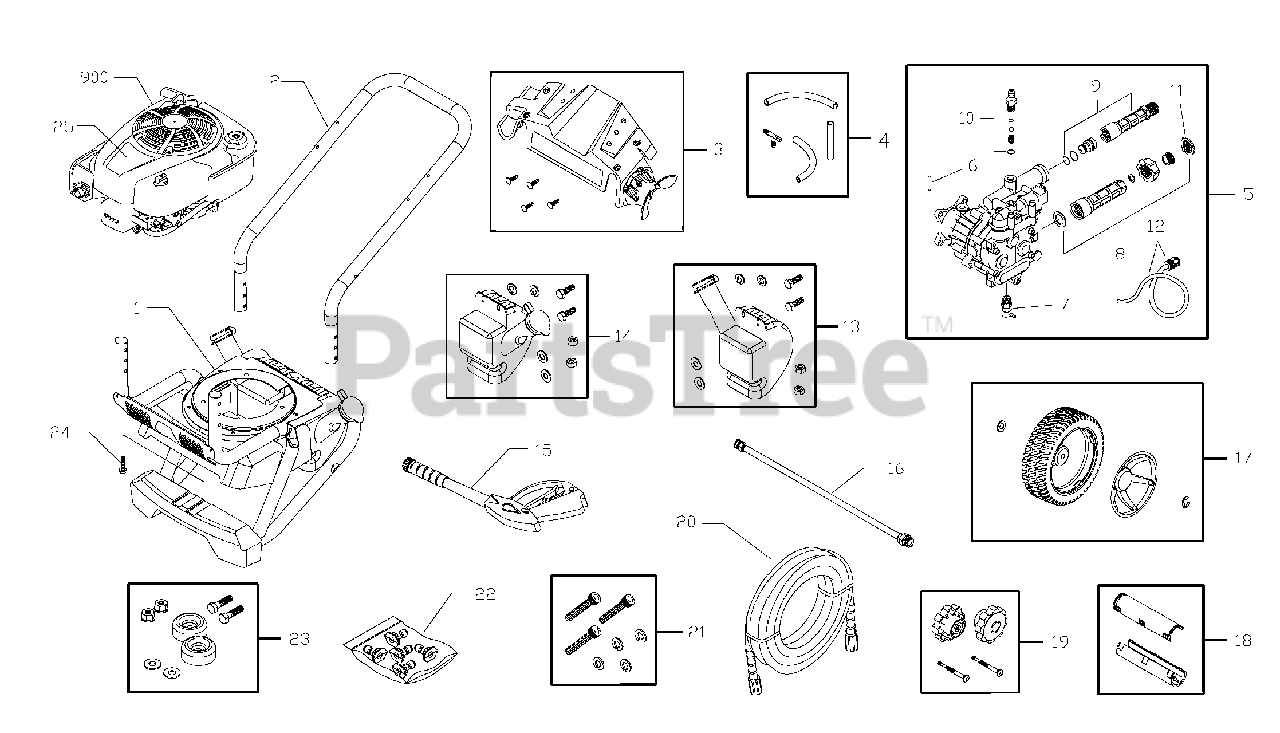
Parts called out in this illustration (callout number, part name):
7	VALVE, Thermo Relief
8	KIT, Water Inlet
9	KIT, Water Outlet
10	KIT, Chemical Injection
11	FILTER, Garden Hose
15	GUN
16	EXTENSION, QC
19	KIT, Hardware, Handle
21	KIT, Hardware, Pump Mounting
22	KIT, QC Nozzles
23	MOUNT, Vibration
900	* ENGINE
